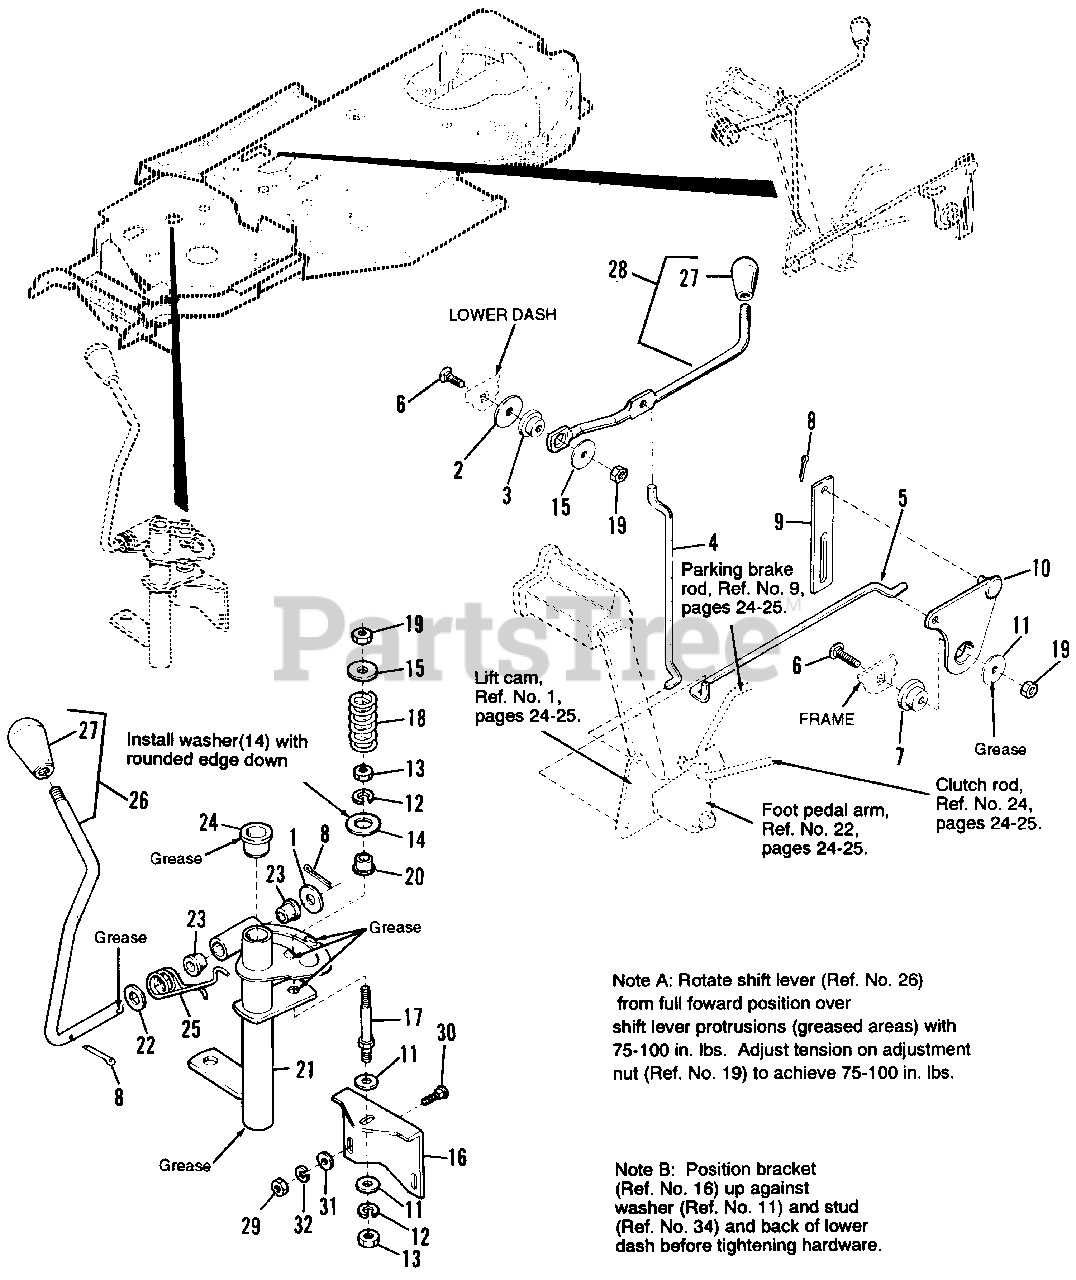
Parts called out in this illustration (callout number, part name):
1	WASHER, 1/2
2	WASHER, Plain, 13/32 x 1-1/2 x 1/8
3	SPACER, Special
4	LINK, Lift Upper
6	CARRIAGE BOLT, 5/16-18 x 1-1/2
7	SPACER, Special
8	COTTER PIN
9	LINK, Lift, Upper Transport
10	CAM, Lift Assy.
11	WASHER, Plain, 21/64 x 1-1/4
12	LOCKWASHER, 5/16
13	NUT, Hex, 5/16-18
14	WASHER, H.T.
15	WASHER, Plain, 5/16
16	BRACKET, Tension
17	STUD, 5/16-18 x 3-1/4
18	SPRING, Compression
19	NUT, Hex, Esna, Lock, 5/16-18
21	SHIFT LEVER ASSY.
22	WASHER, Plain
23	BUSHING, Plastic, 1/2 Dia.
24	BUSHING, Nylon, 3/4 Dia.
25	SPRING, Torsion
26	LEVER, Shift (Incl. Ref. No. 27)
27	KNOB, Plastic
28	ROD, Lift Handle (Incl. Ref. No. 27)
29	NUT, Hex, 1/4-20
30	CARRIAGE BOLT, 1/4-20 x 3/4
31	WASHER, Plain, 1/4
32	LOCKWASHER, 1/4
